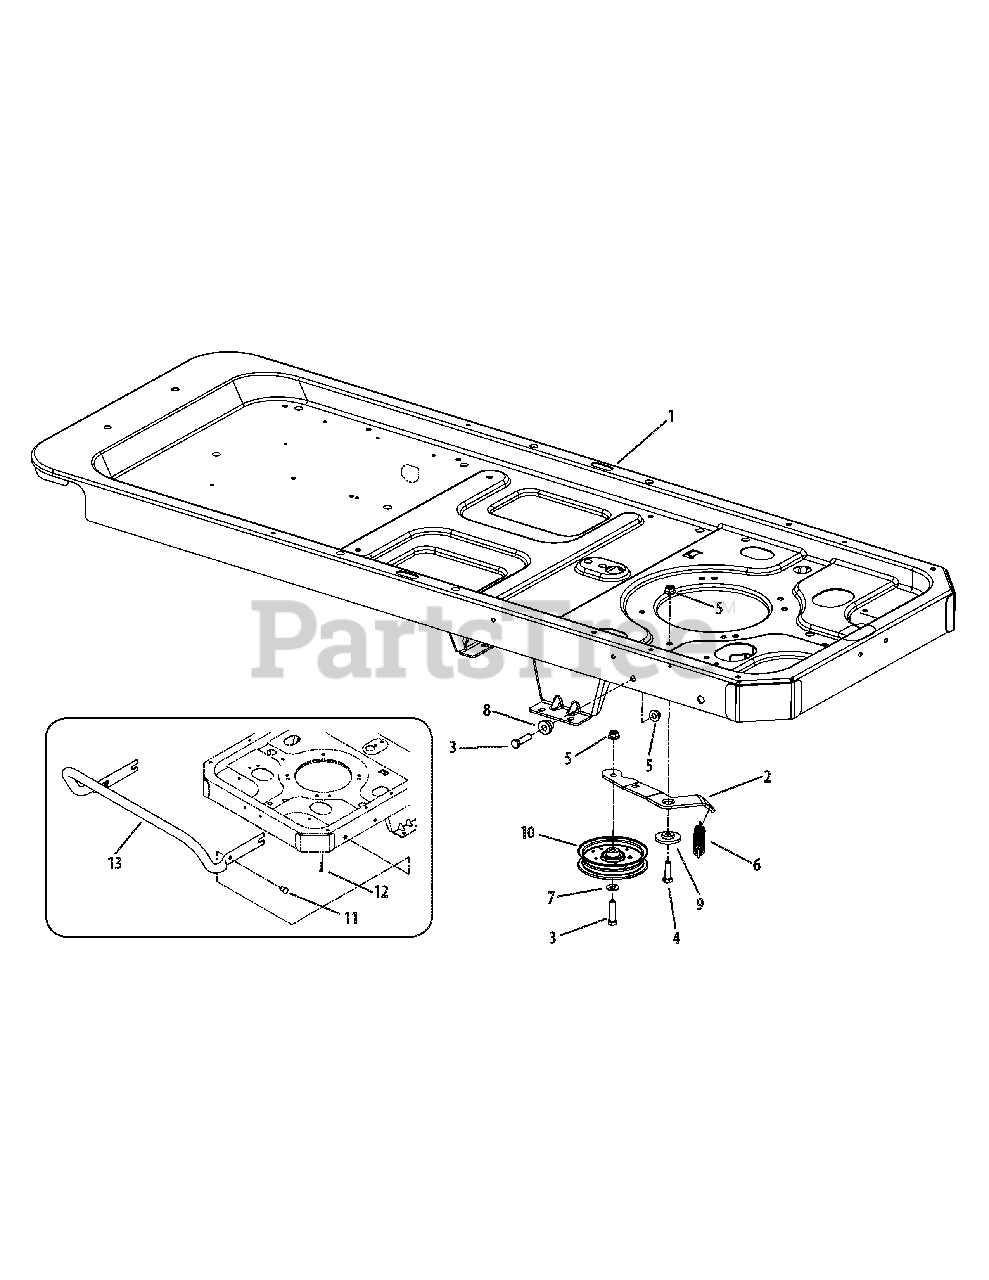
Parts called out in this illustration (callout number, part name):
1	Frame
3	Hex Cap Screw, 3/8-16 x 1.5
4	Hex Cap Screw, 3/8-16 x 1.25
5	Hex Flange Lock Nut, 3/8-16
6	Extension Spring, .75 x 5.06
7	Flat Washer, .406 x .875 x.059
8	Shoulder Spacer, .38 x 1.0 x .7
9	Shoulder Spacer, .884 x 1.9
10	Idler Pulley
11	Clevis Pin, .50 x .78
12	Cotter Pin, .080 x 1.5625
